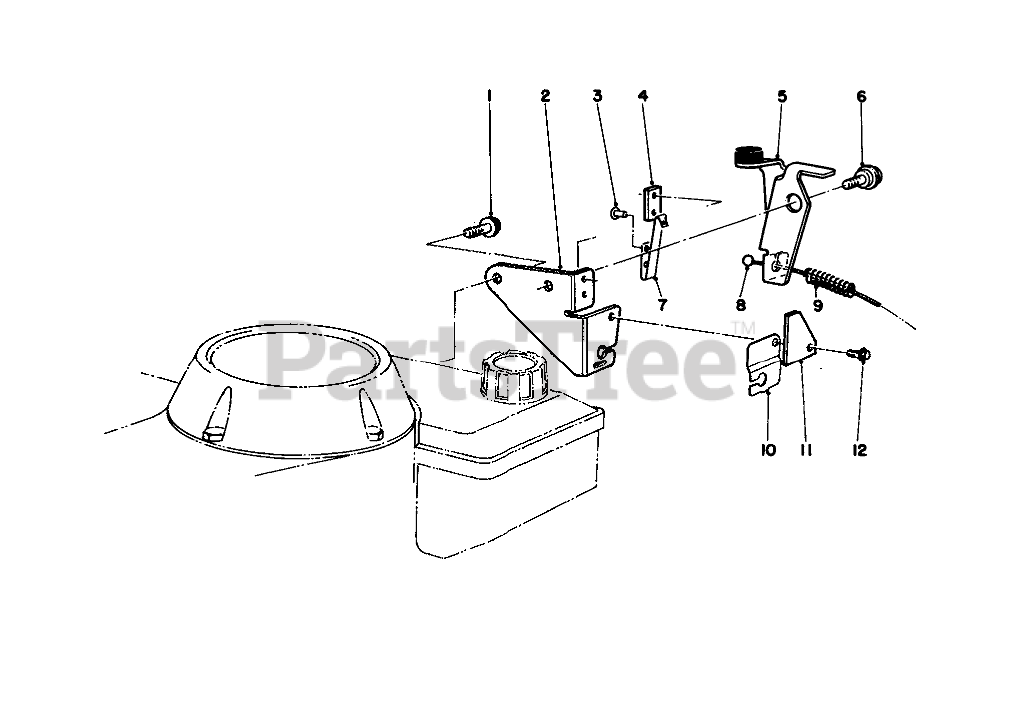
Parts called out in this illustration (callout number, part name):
1	THO FORM SCREW M6 X 1
2	Plate-Mounting
3	RIVET-PLASTIC
4	Strap-Insulation
5	BRAKE PLATE ASM
6	Screw-Shoulder
7	STRAP-GROUND
8	BRAKE CABLE
9	SPRING-COMPRESSION
10	CABLE CLAMP
11	STOP-GROUND STRAP
12	SCREW
